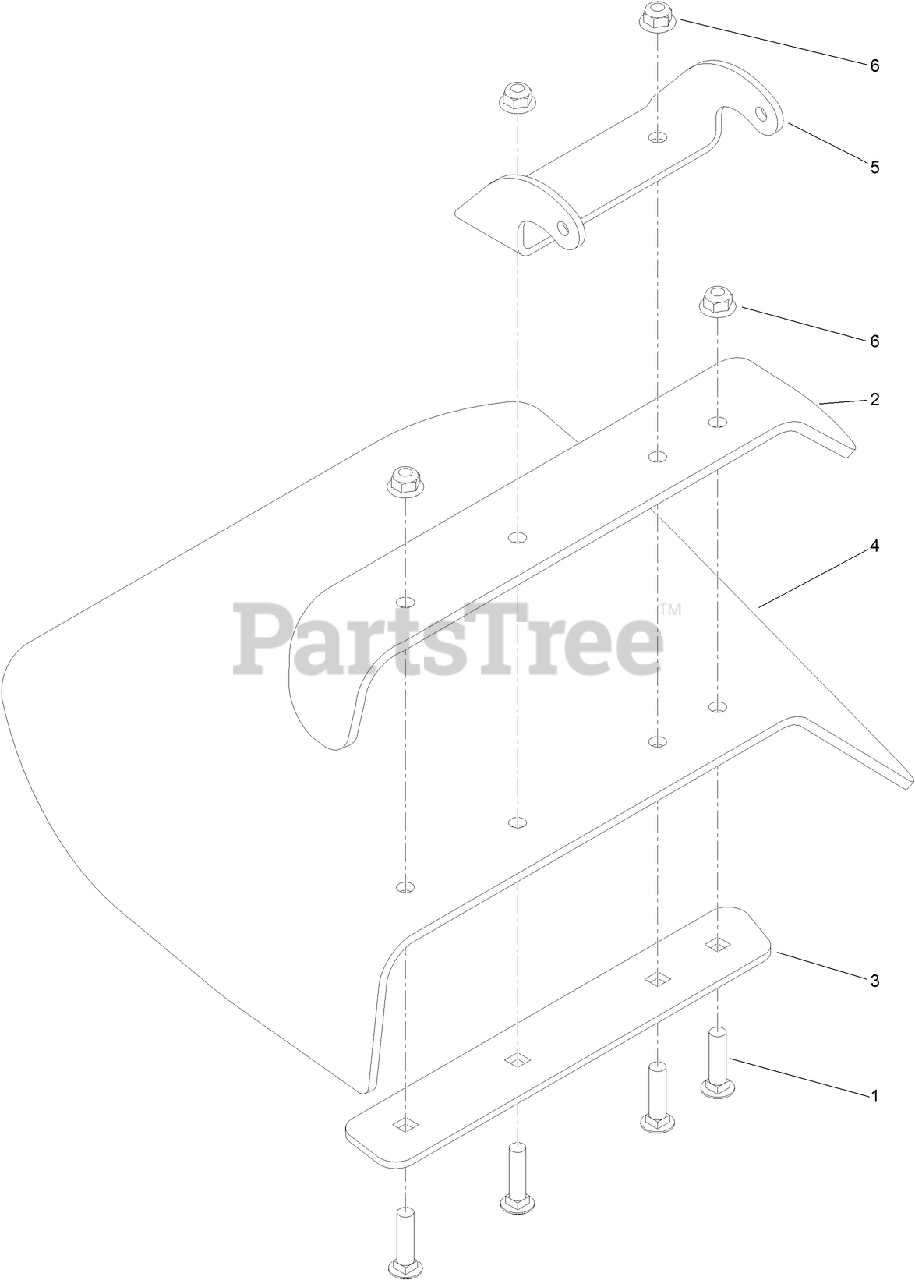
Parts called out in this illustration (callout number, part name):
1	SCREW-CARR
2	DEFLECTOR
3	STRAP-DISCHARGE
4	DEFLECTOR-RUBBER
5	BRACKET-MOUNTING, DEFLECTOR
6	NUT-HF, NI
